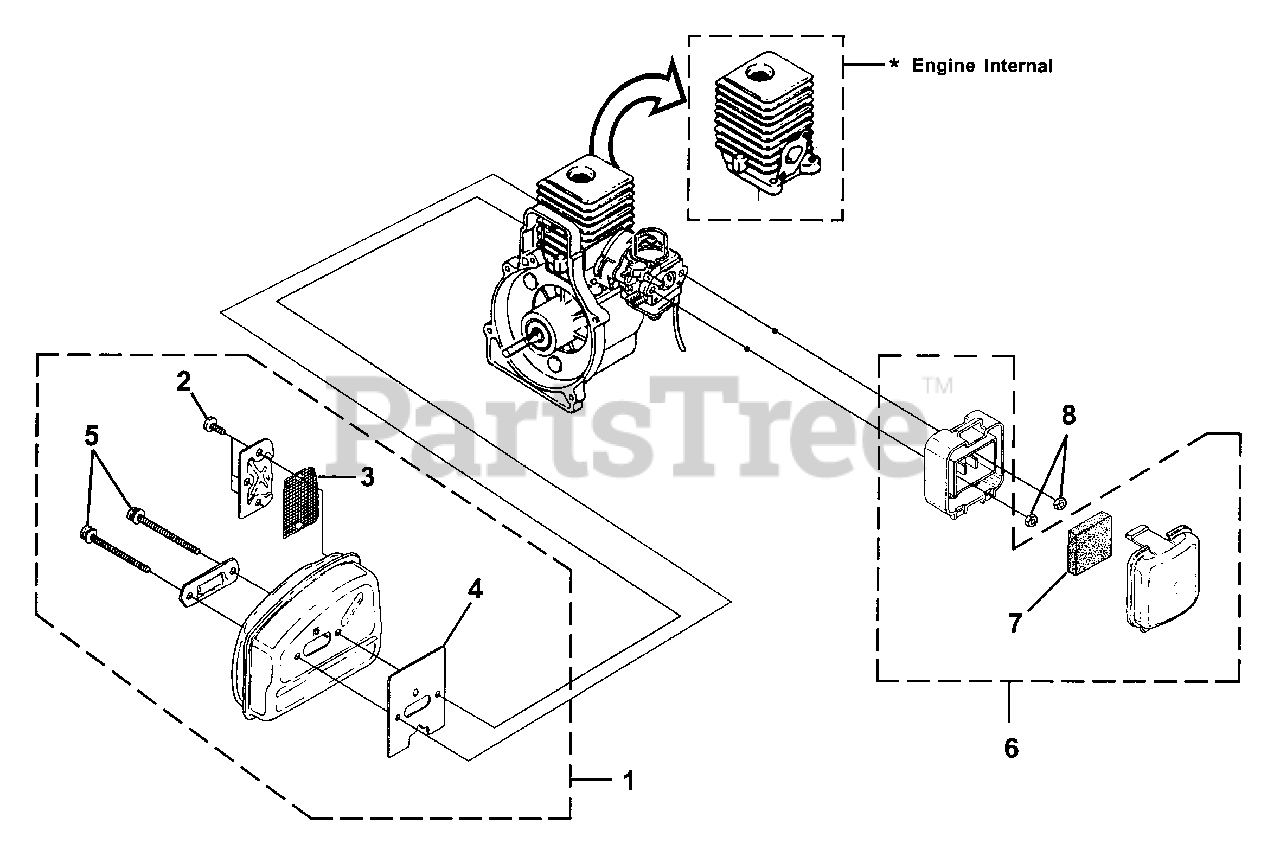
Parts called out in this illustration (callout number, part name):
1	MUFFLER ASSY.
2	SCREW, Taptite - (8-32 X 3/8")
3	SCREEN-Spark
4	GASKET-Muffler
5	SCREW, Truss Hd. - (10-24 X 2.188)
6	AIR FILTER KIT
7	FILTER-AIR
8	NUT-Hex (10-24)
